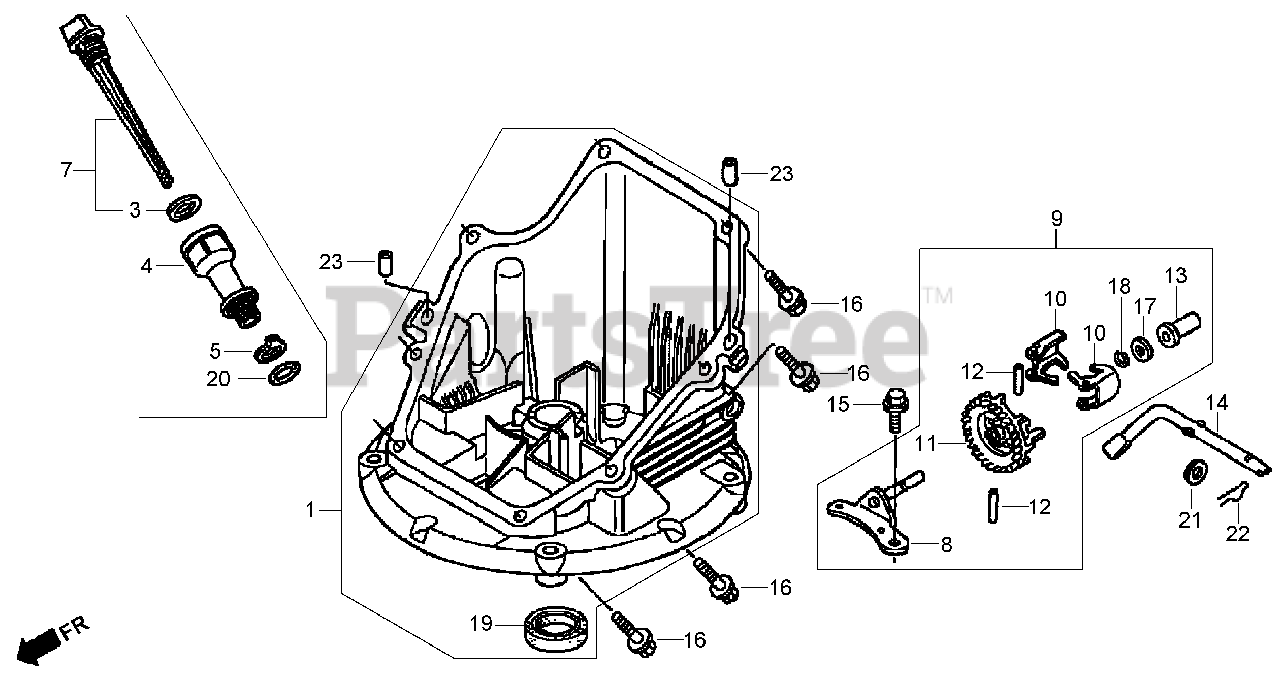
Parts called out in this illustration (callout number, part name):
1	OIL PAN ASM
3	GASKET-CAP, OIL FILLER
4	EXTENSION-FILLER, OIL
5	WASHER-LOCK, EXTENSION
7	OIL LEVEL GAUGE ASM
8	SHAFT-HOLDER, GOVERNOR
9	GOVERNOR ASM
10	WEIGHT-GOVERNOR
11	HOLDER-WEIGHT, GOVERNOR
12	PIN-WEIGHT, GOVERNOR
13	SLIDER-GOVERNOR
14	SHAFT-ARM, GOVERNOR
15	BOLT-FLANGE (6X14) (C T200)
16	BOLT-FLANGE (6X25) (C T 200)
17	WASHER-THRUST (6MM)
18	CLIP-HOLDER, GOVERNOR
19	SEAL-OIL (28X41.25X6)
20	O-RING (14.8X24) (N O K)
21	WASHER-PLAIN (6MM)
22	PIN-LOCK (8MM)
23	PIN-DOWEL (8X20)
